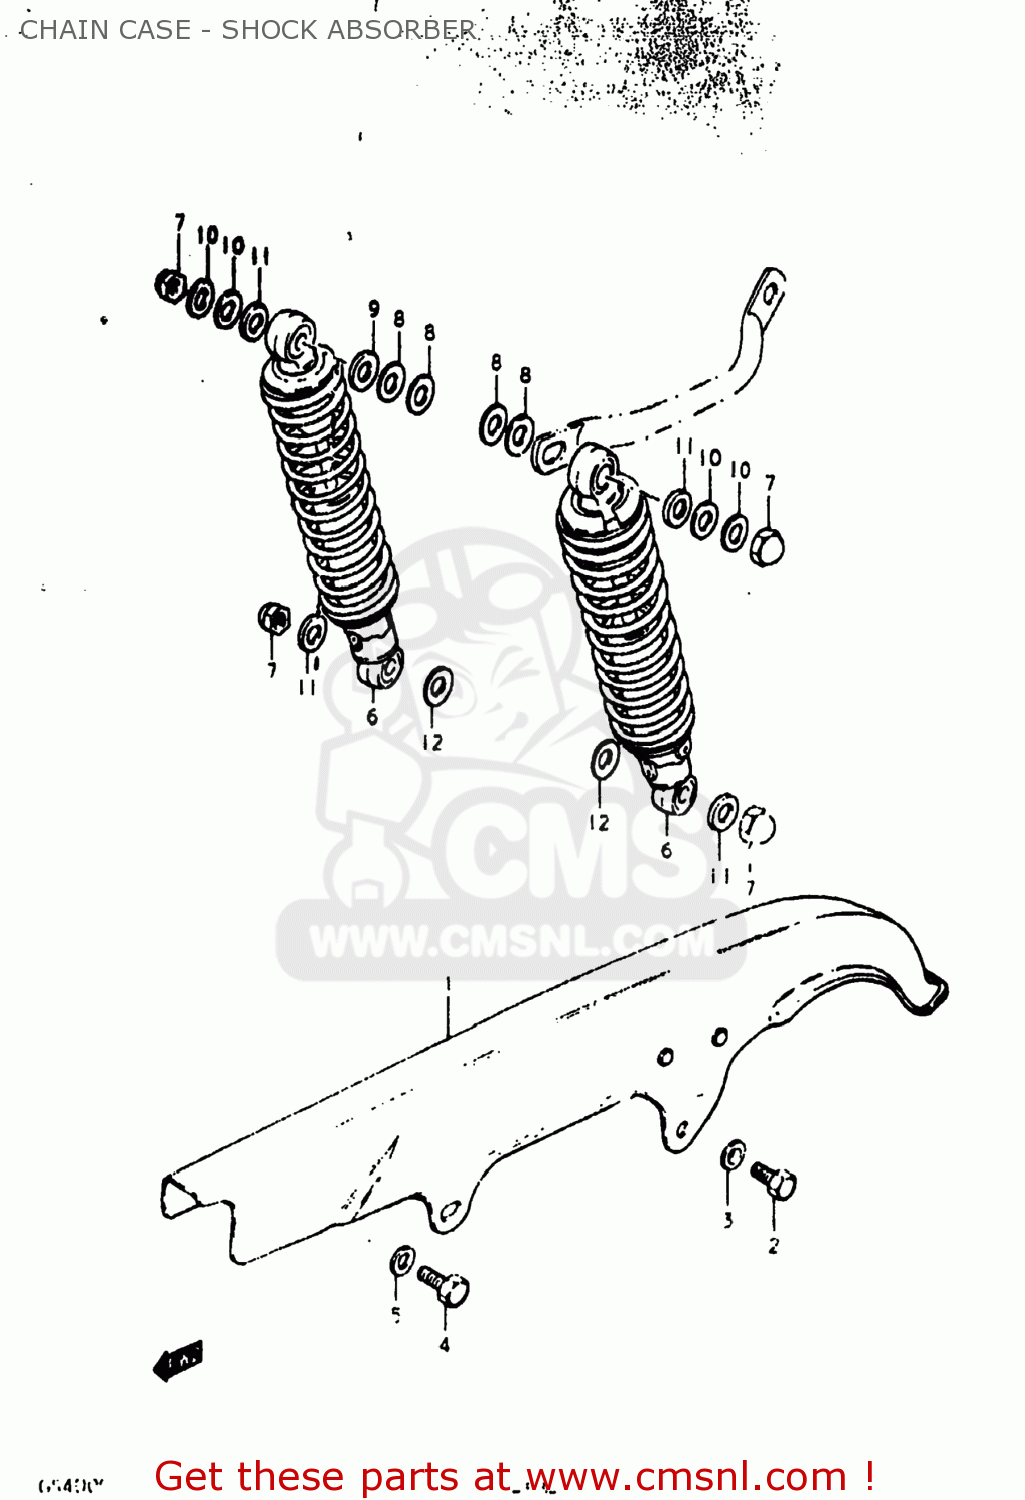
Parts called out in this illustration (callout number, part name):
1	CASE,CHAIN
2	BOLT(6X8)
3	WASHER
4	BOLT
5	WASHER(6.5X18X1)
6	ABSORBER ASSEMBLY,REAR SHOCK
7	NUT, LOWER LH
8	WASHER
9	WASHER (12.5X24X3.2)
10	WASHER
11	WASHER(10.5X24X3.2)
12	WASHER (12.5X24X1.6)
